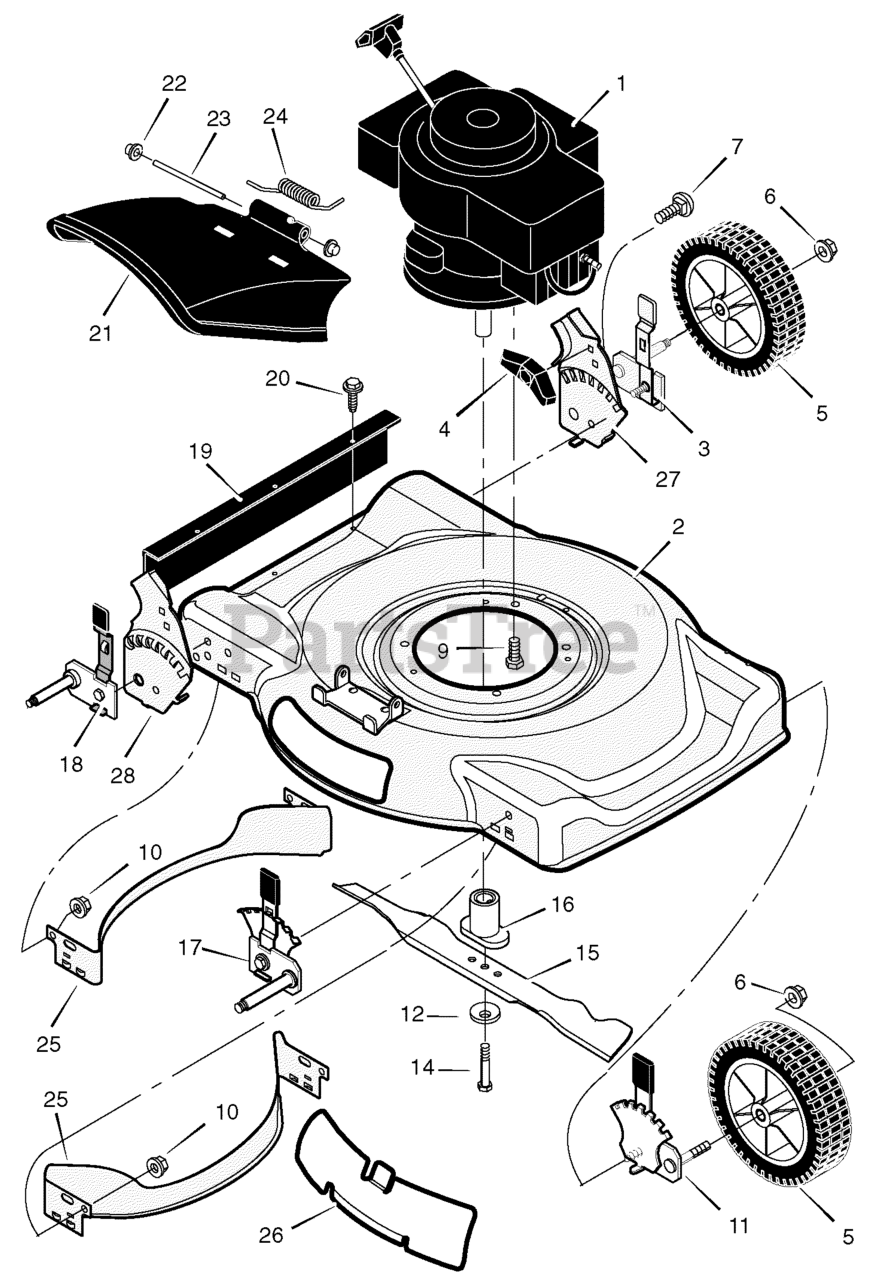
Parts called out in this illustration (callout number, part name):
1	Engine *
2	Housing
3	Height Adjuster, Left Rear (8" Wheels)
5	Wheel and Tire
6	Locknut, Flange
7	Bolt, Carriage
9	Bolt, Engine
10	Nut
11	Height Adjuster, Left Front (8" Wheels)
12	Washer, Belleville
14	Bolt, Hex
16	Adapter, Blade
17	Height Adjuster, Right Front (8" Wheels)
18	Height Adjuster, Right Rear (8" Wheels)
19	Guard, Rear
21	Deflector, Chute
22	Push-On Cap
23	Pin, Pivot
24	Spring
25	Baffle Optional Accessory
26	Plate, Mulcher
27	Bracket, Left Handle
28	Bracket, Right Handle
